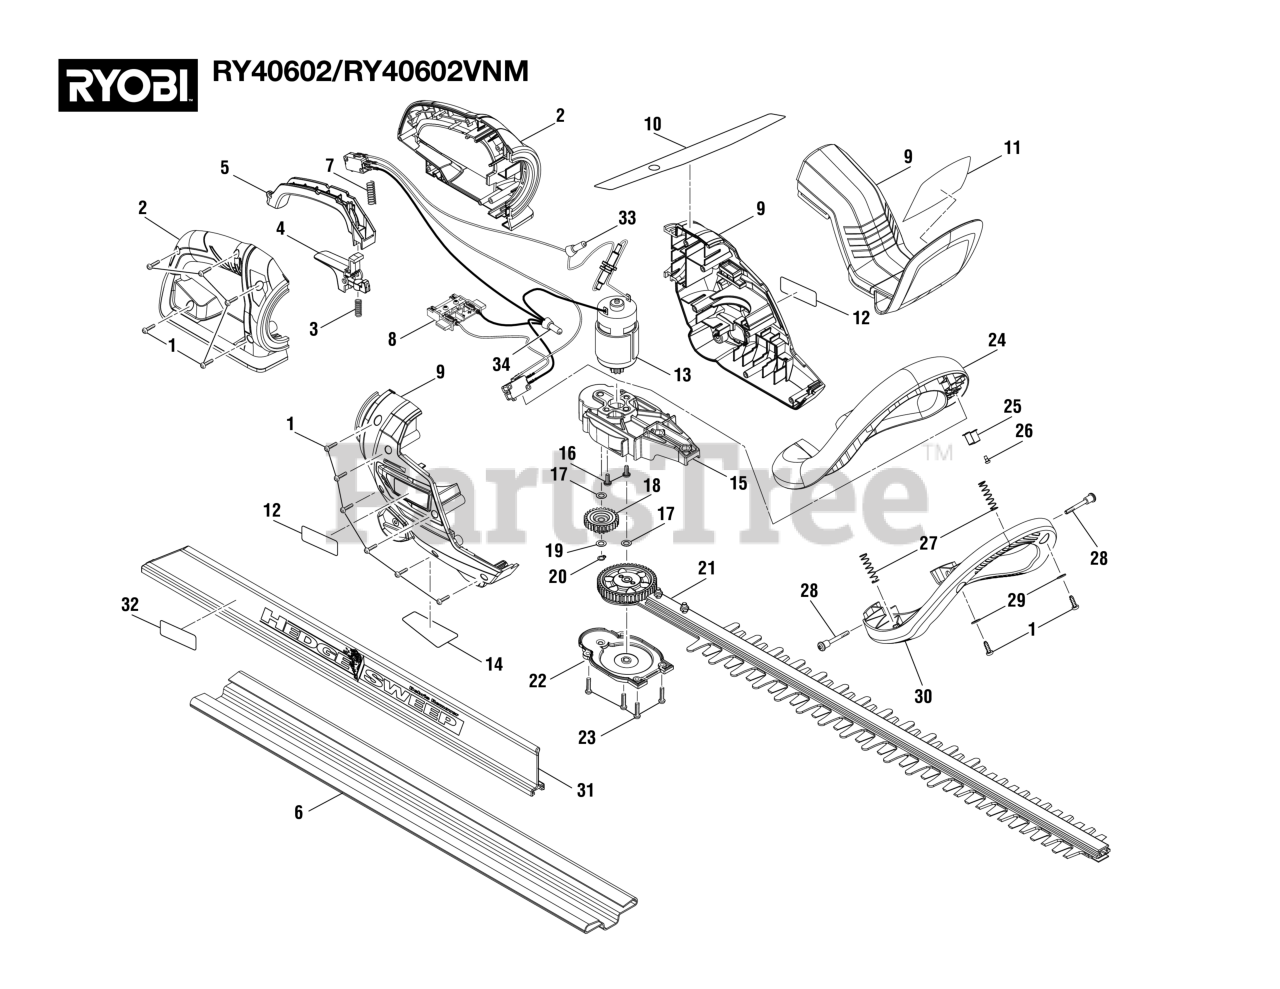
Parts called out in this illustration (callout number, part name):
1	Screw (M4 x 13.5 mm, T15 Torx Pan Hd.)
2	Motor Housing Assembly (Inc. Key Nos. 10-12 & 14)
3	Compression Spring
4	Lock-off Trigger Assembly
6	Scabbard, PP
7	Compression Spring
8	Switch and Contact Plate Assembly
9	Rear Handle Assembly
10	Angle Adjustment Label
11	Warning Label
12	Logo Label
13	Motor Assembly
14	Data Label
15	Gear Case
16	Screw w/Tooth Washer (M4 x 12 mm, Pan Hd.)
17	Washer (M6, ID6.2 x 11OD x 0.3t)
18	Middle Gear Assembly
19	Flat Washer (OD10 x ID5.3 x 0.5t)
20	Retaing Ring
21	Blade Assembly (24 in.)
22	Gear Case Cover
23	Screw (M4 x 16 mm, Pan Hd.)
24	Front Handle
25	Switch Board, SPCC, Black Zinc Plated
26	SCREW, CH M3 PH B\L=6MM
27	Spring,Handle Cover, Dia. 7, SWC
28	Screw (M4 x 38 mm, T20 Torx Pan Hd.)
29	Flat Washer (OD10 x ID42 x 1t)
30	Front Handle Cover
31	Hedge Sweep (Inc. Key No. 32)
32	Warning Label
33	Wire Connector (Closed End)
34	Wire Connector (Closed End)
